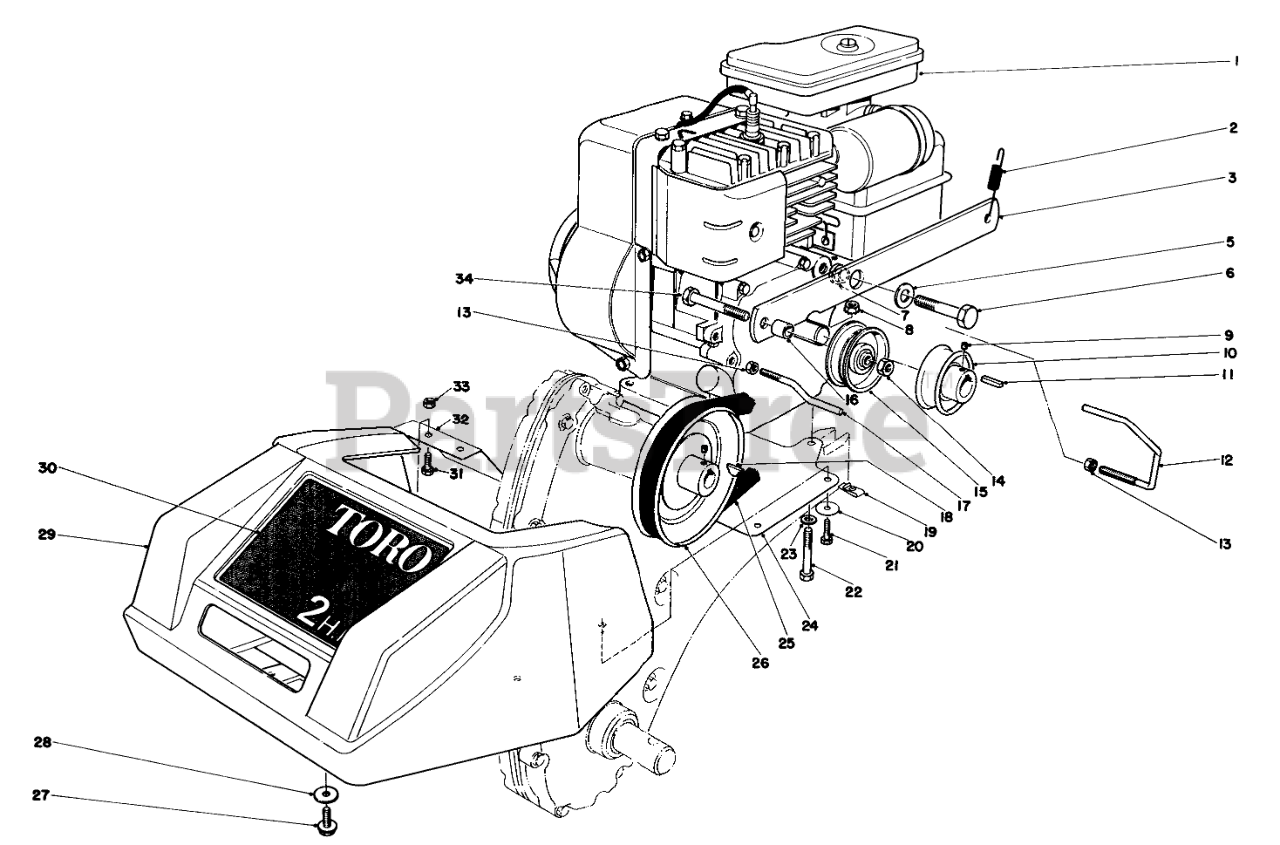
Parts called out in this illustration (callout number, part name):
1	Engine (Model 58307)
2	TENSION SPRING
3	Idler Arm
5	WASHER-FLAT
6	SCREW-HH
7	Spacer Idler Arm
8	NUT-KEPS
9	SCREW-HSH
10	Driver Pulley (Model 58307)
11	KEY-SQUARE
12	Belt Guide
13	NUT-HEX
14	NUT-LOCK, SIDE
15	Idler Pulley
16	Spacer
17	Belt Guide
18	KEY-WOODRUFF
19	NUT-SPEED
20	WASHER CONTROL PIVOT
22	SCREW-HH
23	WASHER-PLAIN
24	Mtg. Plate-Shroud
25	V-Belt
26	Driver Pulley
27	Screw
28	WASHER-FLAT
29	Shroud
30	Decal (Model 58307)
31	SCREW-HH
32	Shield
33	NUT-LOCK
34	SCREW-HH
